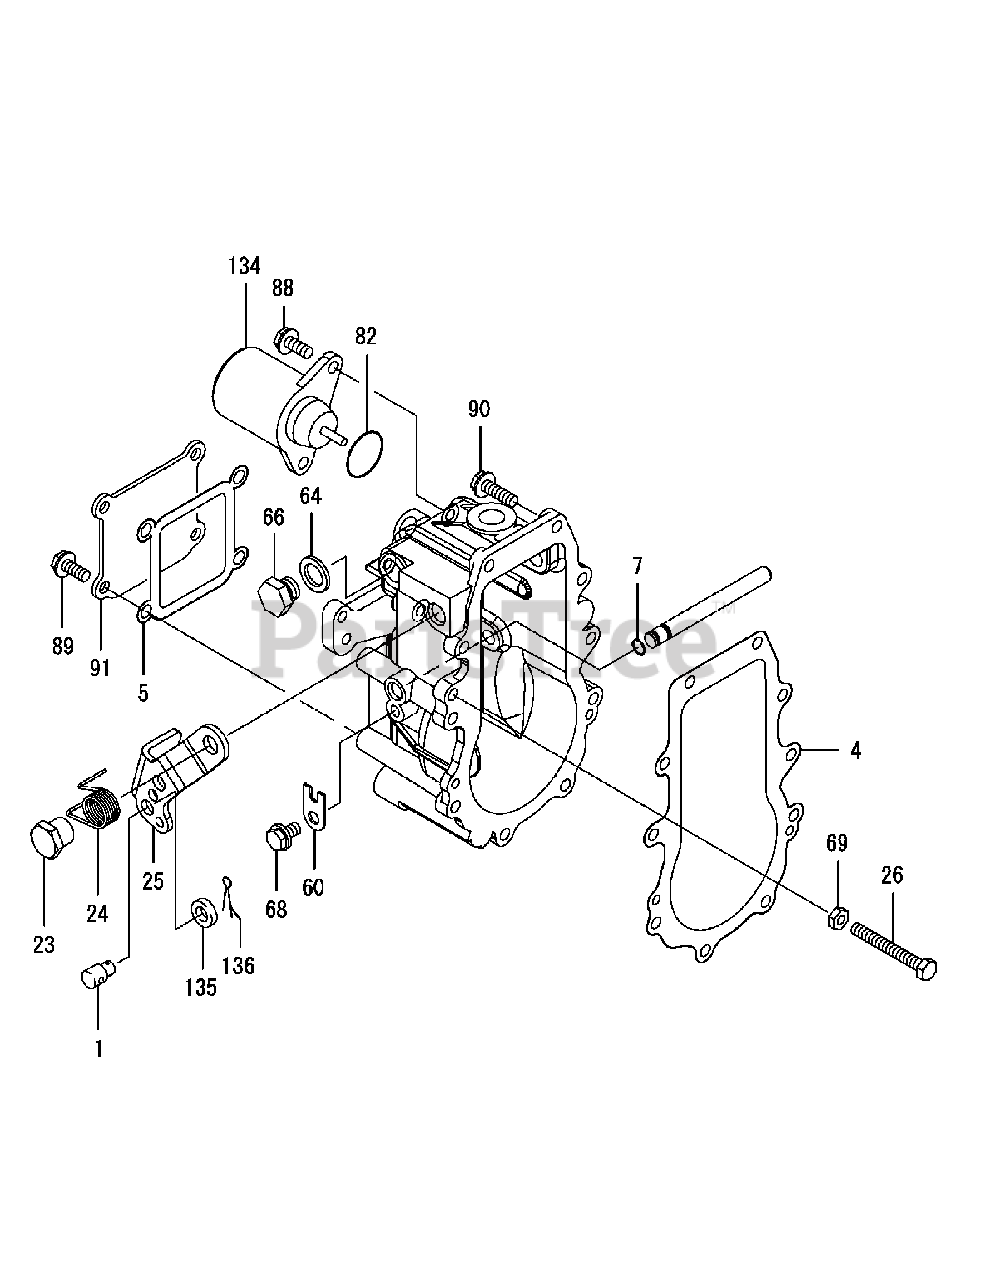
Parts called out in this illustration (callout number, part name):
5	PACKING, COVER
24	SPRING, RETURN
25	LEVER, REGULATOR
60	RETAINER, SHAFT
64	SEAL WASHER 12(BOLT)
68	BOLT 6X 10 PLATED
88	BOLT M 6X 14 PLATED
89	BOLT M 6X 14 PLATED
90	BOLT M 6X 20 PLATED
91	COVER, GOVERNOR CASE
134	SOLENOID, STOP
135	WASHER 8, POLISHED
136	COTTER PIN 1.6X18
